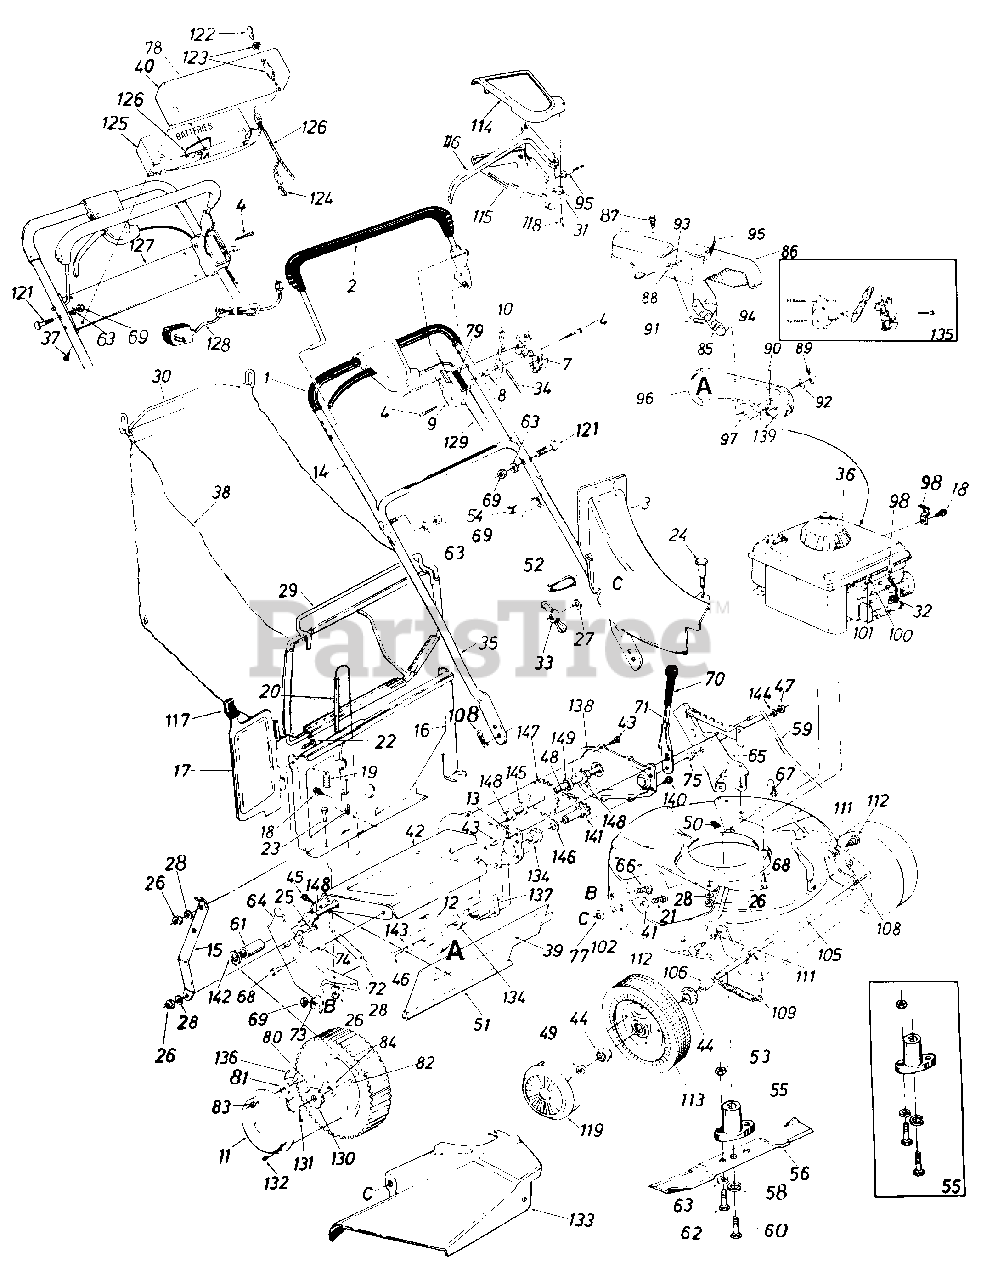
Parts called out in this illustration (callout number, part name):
2	Control Handle Ass'y.-L.H.
3	Top Discharge Chute Ass'y.
4	Truss Mach. Scr. #12 x 1.50" Lg.
7	Control Panel Half
8	Control Disc Pin
9	Clutch Panel Half
10	Throttle Control Lever
11	Hub Cap
12	1/2" V-Pulley
13	Cotter Pin 3132" Dia. x .751"*
14	Upper Handle-Chrome
15	Panel Support Brkt.
16	Top Catcher Panel
17	Top Door
18	Hex B-Tap Scr. #10 x .38"
19	Torsion Spring
20	Pivot Pin
21	Carriage Bolt 1/4-20 x .62"*
22	Truss Mach. Scr. 1/4-20 x .62" Lg.
23	Hex Bolt 1/4-20 x .50" Lg.*
24	Shoulder Bolt .312 Dia. x .18 Lg. Special
25	Hex Bolt 1/4-20 x .62" Lg.
26	Hex Nut 1/4-20 Thd.*
27	Fl-Wash. .280" I.D. x .620"
28	L-Wash. 1/4" I.D.*
29	Front Grass Catcher Frame
30	Grass Catcher Handle
31	S.P. Control Cover
32	Spark Plug Insulator
33	Wing Nut
34	Throttle Control Wire 58"
35	Lower Handle-Chrome
36	Engine
37	Truss Mach. Hi-Riser Tap Scr. 1" Lg.
38	21" Top Discharge Grass Bag
39	Retaining Strip
40	Battery Tray
41	Fl-Wash. .344" I.D. x .62"
42	Chain-Axle Ass'y.
43	Hex B-Tap Scr. 1/4" x .38" Lg.
44	Flange Ball Bearing 1/2" I.D.
45	Hex AB-Tap Scr. 1/4 x .62"
46	Hex Wash. TT-Tap Scr. 1/4-20
47	Hex Patch L-Nut 3/8-24 Thd.
48	#48 Chain .500" Pitch x .30 Links
49	Hex L-Nut 1/2-20 Thd.
51	Rear Flap 3.75" x 17.30" Lg.
52	Cable Tie
53	Hex Nut 5/16-24 Thd.*
54	Cable Anchor
55	Blade Adapter Kit
56	21" Blade
58	L-Wash. 3/8" I.D.-H.D.
59	Height Adj. Rod 19.42" Lg.
60	Hex Bolt 3/8-24 x 2.25" Lg. (Grade 5)
61	Spacer .51" I.D. x .69" O.D. x.69" Lg.
62	Hex Bolt 5/16-24 x 1.00" Lg. (Grade 5)
63	L-Wash. 5/16" I.D.*
64	R.H. Handle Wheel Brkt. Ass'y.
65	L.H. Handle Wheel Brkt. Ass'y.
66	Carriage Bolt 5/16-18 x .62"*
67	Hex Wash. Hd. B-Tap Scr. 5/16-1 8
68	Hex Wash. Hd. TT-Tap Scr. 3/8-16
69	Hex Nut 5/16-18 Thd.
71	Height Adj. Lever
72	Extension Spring .50" O.D. x 3.80" Lg.
73	Bell-Wash. 5/16" I.D.
74	Spacer .385" I.D. x .502" O.D. x .270" Lg.
75	Shld. Spacer .500" Dia. x .100
77	Bolt Retainer 1/4 x .50" O.D.
78	Instruction Label
79	Sontrol Label
80	Shld. Scr. .342" Dia. x .268
81	Pawl
82	Wheel Ass'y. Comp.-Rear 8 x 1.75
83	Hex Ins. L-Nut 1/4-20 Thd.
84	Flange Ball Bearing 1/2" I.D.
85	Belt Idler Bracket Ass'y.
86	Belt Cover
87	Hex Wash. S-Tap Scr. 1/4-20 x.50" Lg.
88	Hex Nut 1/4-20 Thd.
89	Cotter Pin 1/8" Dia. x 1.00" Lg.*
90	Spring Pin Spir. 3/16" Dia. x 1.00" Lg.
91	Extension Spring .33" O.D. x 1.12" Lg.
92	Fl-Wash. .531" I.D. x .930" O.D. x .050
93	--Wash. 1/4" I.D.*
94	Shld. Bolt .375" Dia. x .181
95	S.P. Cable x 53.0" Lg.
96	"V"-Belt 1/2" x 32.0" Lg.
97	Fl-Idler Plastic 1.62" Dia.
98	Casing Clamp
100	Hex B-Tap Scr. #10 x .62"
101	Casing Clamp
106	Sleeve .526" I.D. x .690" O.D. x .880" Lg.
108	Intern. Cotter Pin 5/16" Dia.
109	Extension Spring .50" O.D. x 3.20" Lg.
111	Intern. L-Wash. 3/8 I.D.*
112	Shld. Bolt .623" Dia. x .425
113	Front-Wheel Ass'y. Comp. 7 x 1.50
114	Self-Propelled Control Cover
115	Self-Propelled Control Cover
116	Control Lever
117	Door Grip
118	Fl-"C"-Sunk Hd. Tap Scr. #10 x .75" Lg.
119	Hub Cap-Plastic
121	Curved Carr. Bolt 5/16-18 x 1.38" Lg.
122	Ignition Key
123	Ignition Switch
124	Plug
125	Battery Pack
126	Wire Harness
127	Lower Battery Tray
128	Battery Charger
129	Control Cable-43" Lg.
130	Ratchet Wheel 1.62" O.D.
131	Cotter Pin 1/8" Dia. x 1.00" Lg.*
132	Pan Hd. Tap Scr. #12 x .50" Lg.
133	Side Chute Deflector Ass'y.
134	Flange Bushing
135	Kit-Control Housing Comp.
136	Spring-Nylon
137	Bearing Hub Flange Ass'y.
138	Chain Cover
139	Engine Pulley 1/2"
140	Hex Wash. S-Tap Scr. 1/4-20 x.50" Lg.
141	Sprocket-Shaft Ass'y.
142	Fl-Wash. 531" I.D. x 93 O.D.
143	Bell-Wash. .265" I.D. x .75"O.D.
144	Fl-Wash. .385" I.D. x .87" O.D.
145	Fl-Wash. .51" I.D. x 1.0" O.D.
146	Fl-Wash. .62" I.D. x 1.12"O.D.
147	Rear Shaft Ass'y. 22.05" Lg.
148	Hex Flange Bearing .506" I.D. Plastic
149	Spacer .510" I.D. x 1.00" O.D. x .210" Lg.
